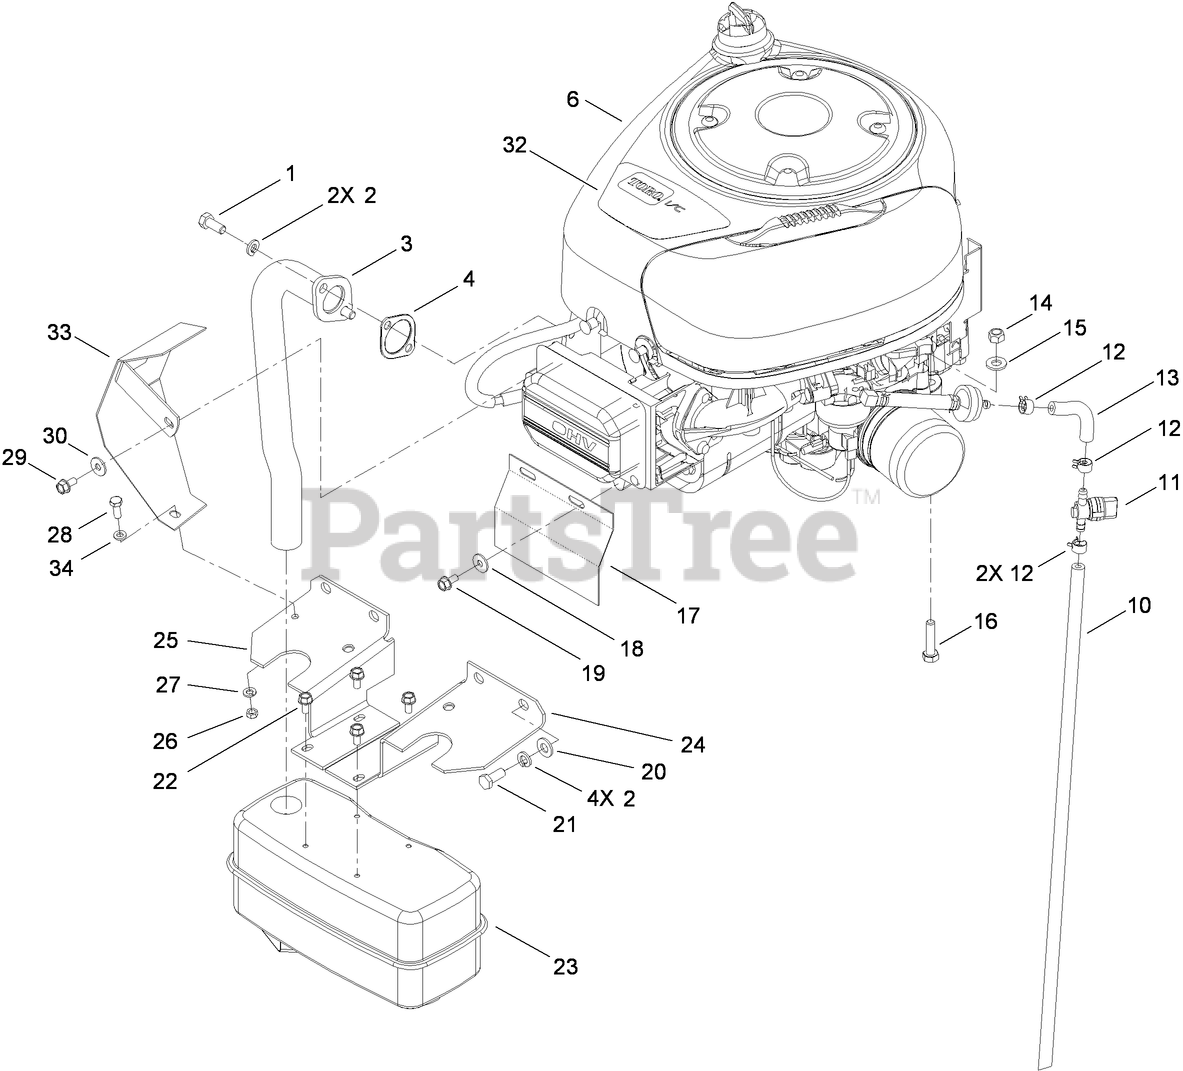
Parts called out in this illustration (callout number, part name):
1	SCREW-HH
3	TUBE-EXHAUST
4	GASKET-EXHAUST
10	LINE-FUEL
11	VALVE-TANK, FUEL
12	CLAMP-LINE, FUEL
13	LINE-FUEL
14	NUT-LOCK, NI
15	WASHER-PLAIN
16	SCREW-HH
17	COVER-FRONT
18	WASHER-FLAT
20	WASHER-PLAIN
21	SCREW-HH
23	MUFFLER
24	GUARD-MUFFLER, LH
25	GUARD-MUFFLER, RH
26	NUT-HEX
27	WASHER-SPRING
28	SCREW-HH
30	WASHER-FLAT
32	DECAL-ENGINE
33	Cover-Manifold, Exhaust
34	WASHER-FLAT
